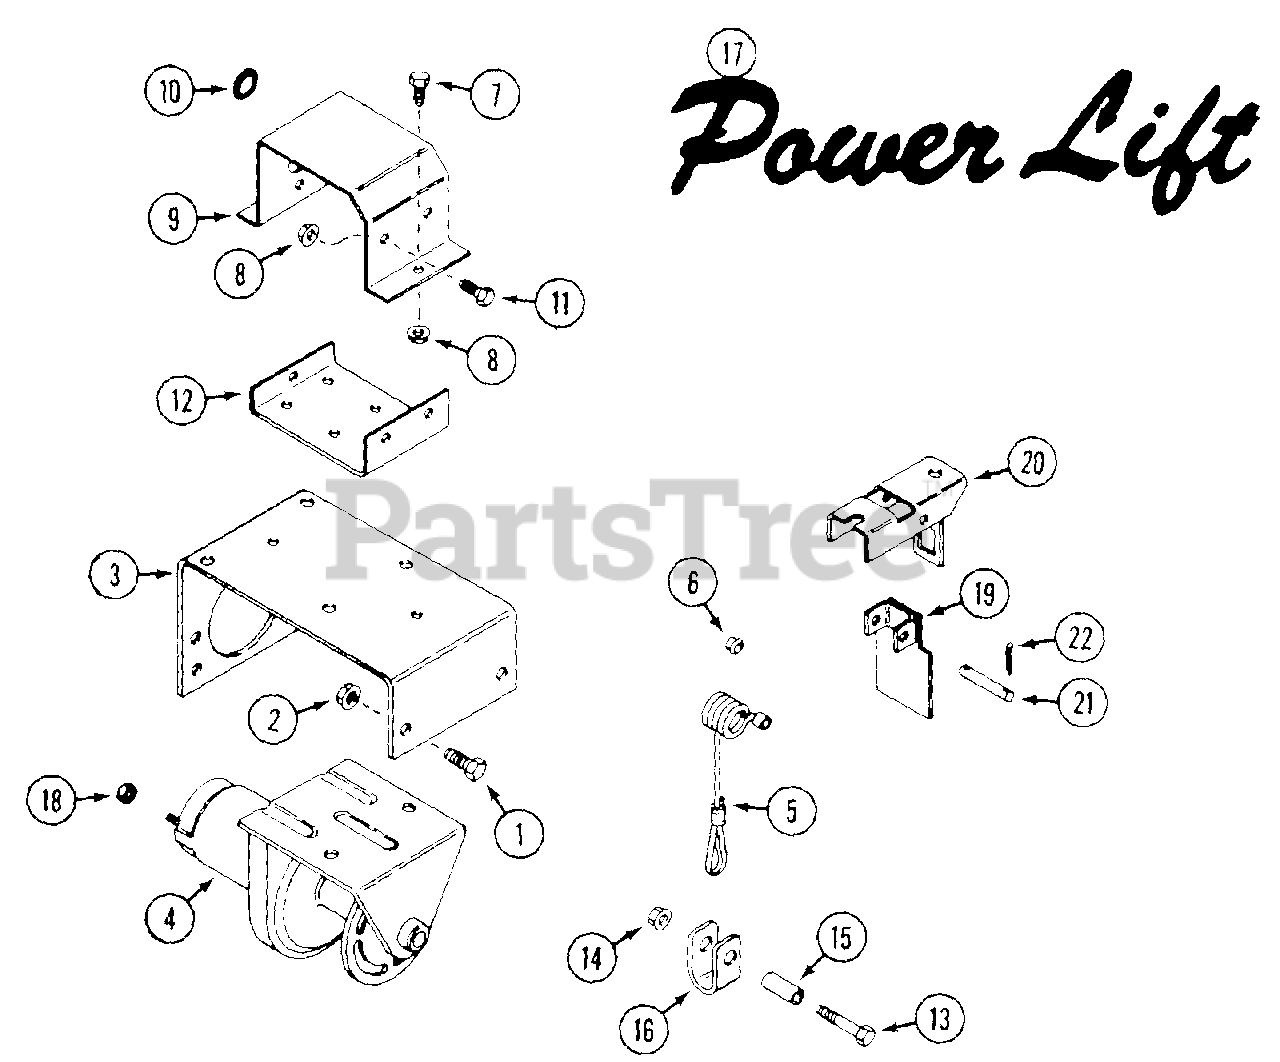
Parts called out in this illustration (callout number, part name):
1	BOLT - 3/8"-16 x 1"
1	SCREW - 3/8"-16 x 1" socket head
2	NUT - 3/8"-16 flange lock
3	MOUNT - winch
4	WINCH - deck lift
6	PIN - cable keeper
7	BOLT - 1/4"-20 x 3/4"
8	NUT - 1/4"-20 flange lock
9	COVER - solenoid
10	GROMMET - 1" x 7/8"
11	BOLT - 1/4"-20 x 1/2"
12	MOUNT - solenoid
13	BOLT - 3/8"-16 x 2"
14	NUT - 3/8"-16 lock
17	DECAL - "Power Lift"
20	MOUNT - trip arm
22	PIN - cotter 1/16" x 5/8"
